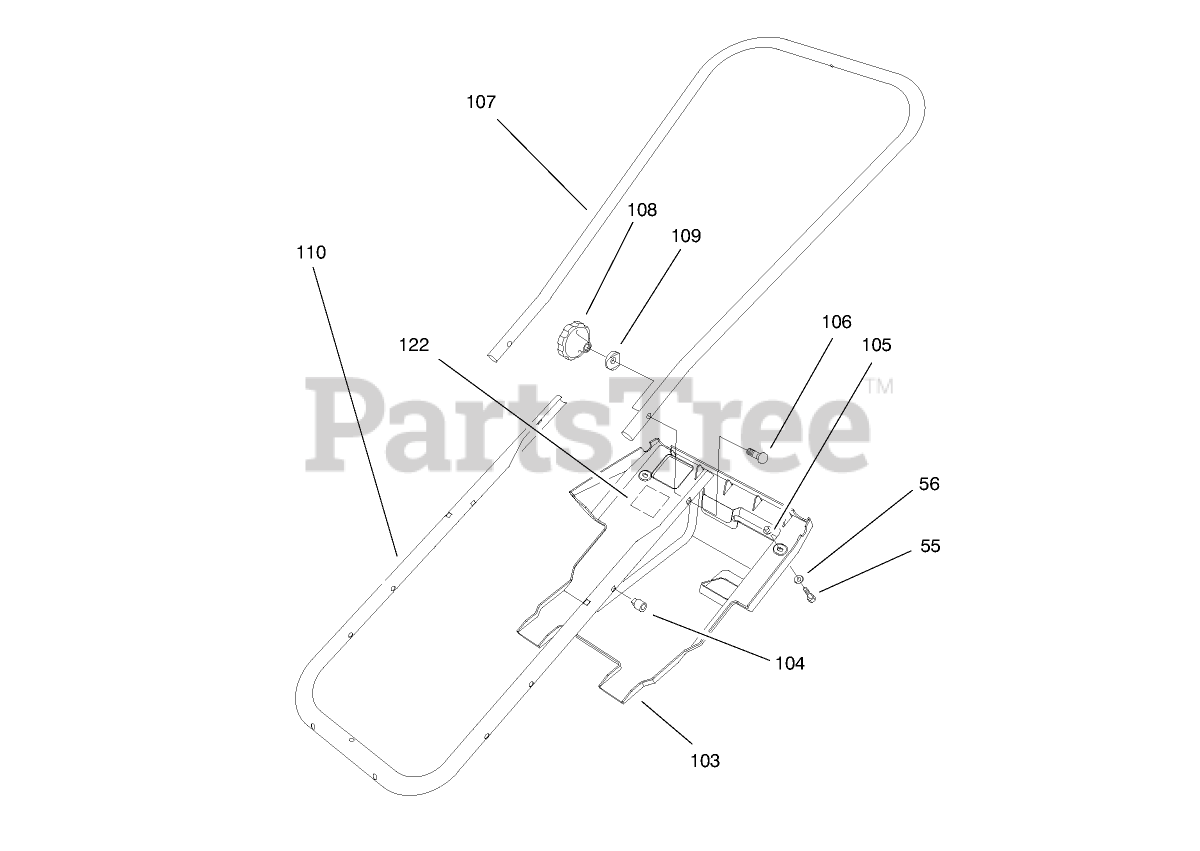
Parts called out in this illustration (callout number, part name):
55	SCREW-HWHTF
56	WASHER-FLAT
103	SHROUD
104	NUT-EXPANSION
105	NUT-CLIP
106	SCREW-HANDLE
122	DECAL
